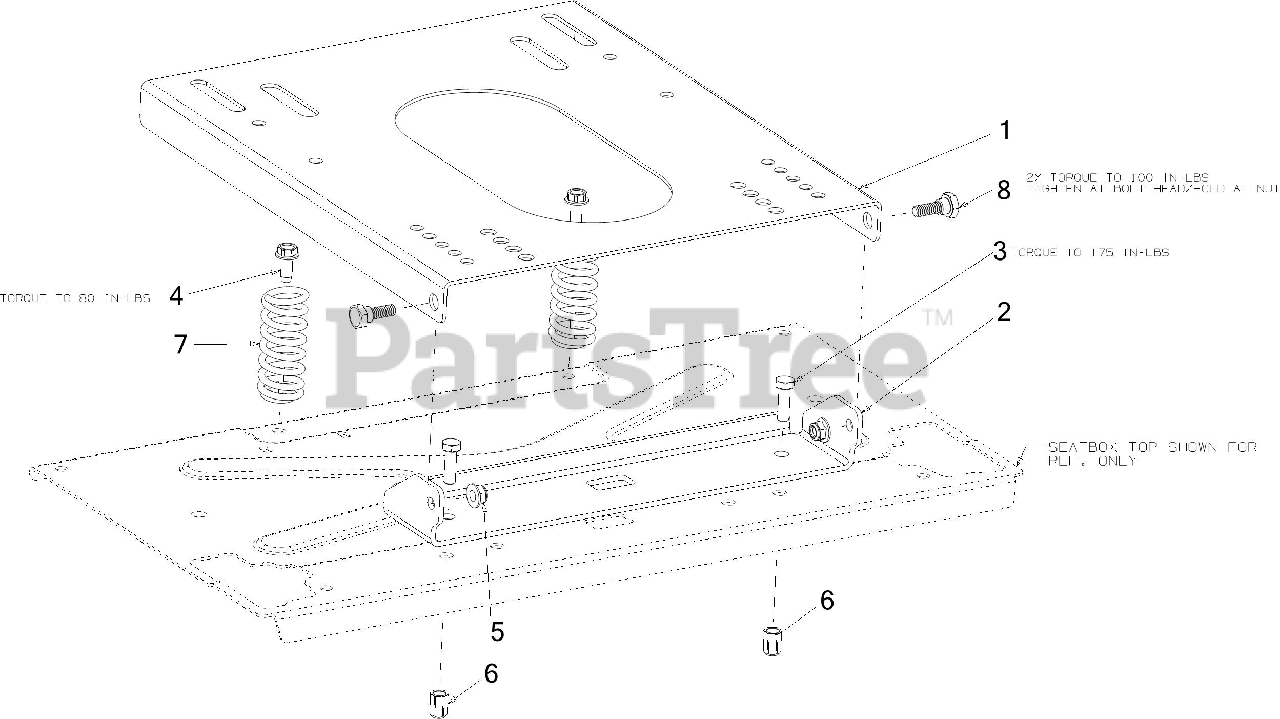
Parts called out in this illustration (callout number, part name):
1	SEAT PLATE DUAL KNOB BASE
2	SEAT PIVOT BRACKET
3	SCREW 5/16-18 x 1.00 GR5
4	SCREW 5/16-18 x .750
5	FLANGE LOCK NUT 5/16-18
6	NUT RIVET 5/16-18
7	COMPRESSION SPRING
8	SHOULDER SCREW .437
